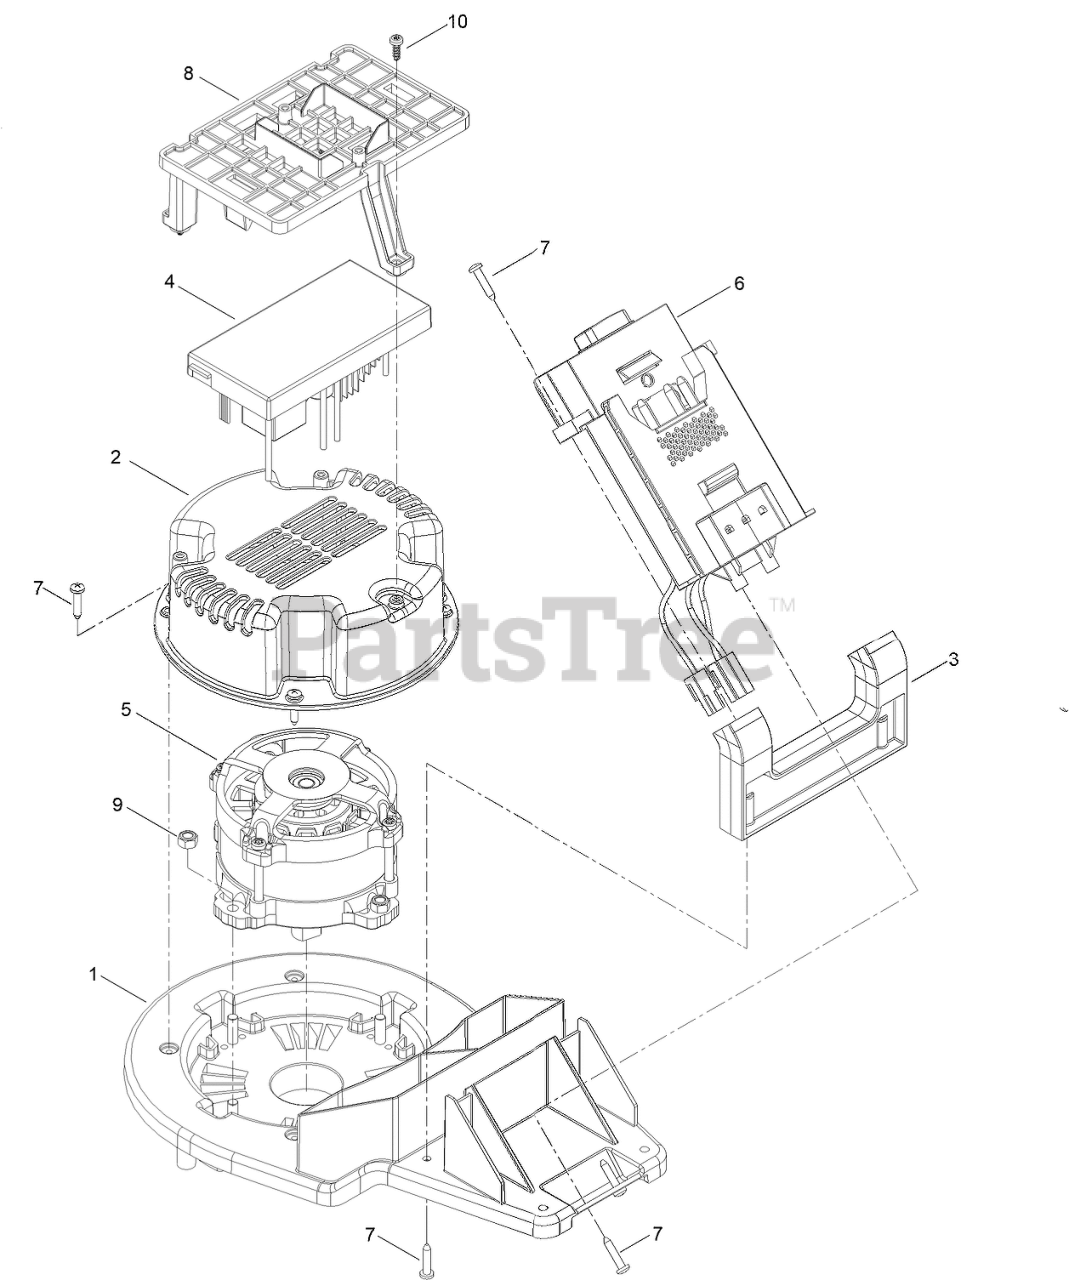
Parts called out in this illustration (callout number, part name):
1	ASM-MOUNT, MOTOR
2	COVER-MOTOR
3	SUPPORT-RECEIVER
4	CONTROLLER-MOTOR, HP
5	MOTOR-1KW, 60V
6	BATTERY TRACK ASM
7	SCREW-PPH, ST4.2x20
8	BRKT-CONTROLLER
9	NUT-HEX, M6
10	SCREW-TPH, ST4.2x12
